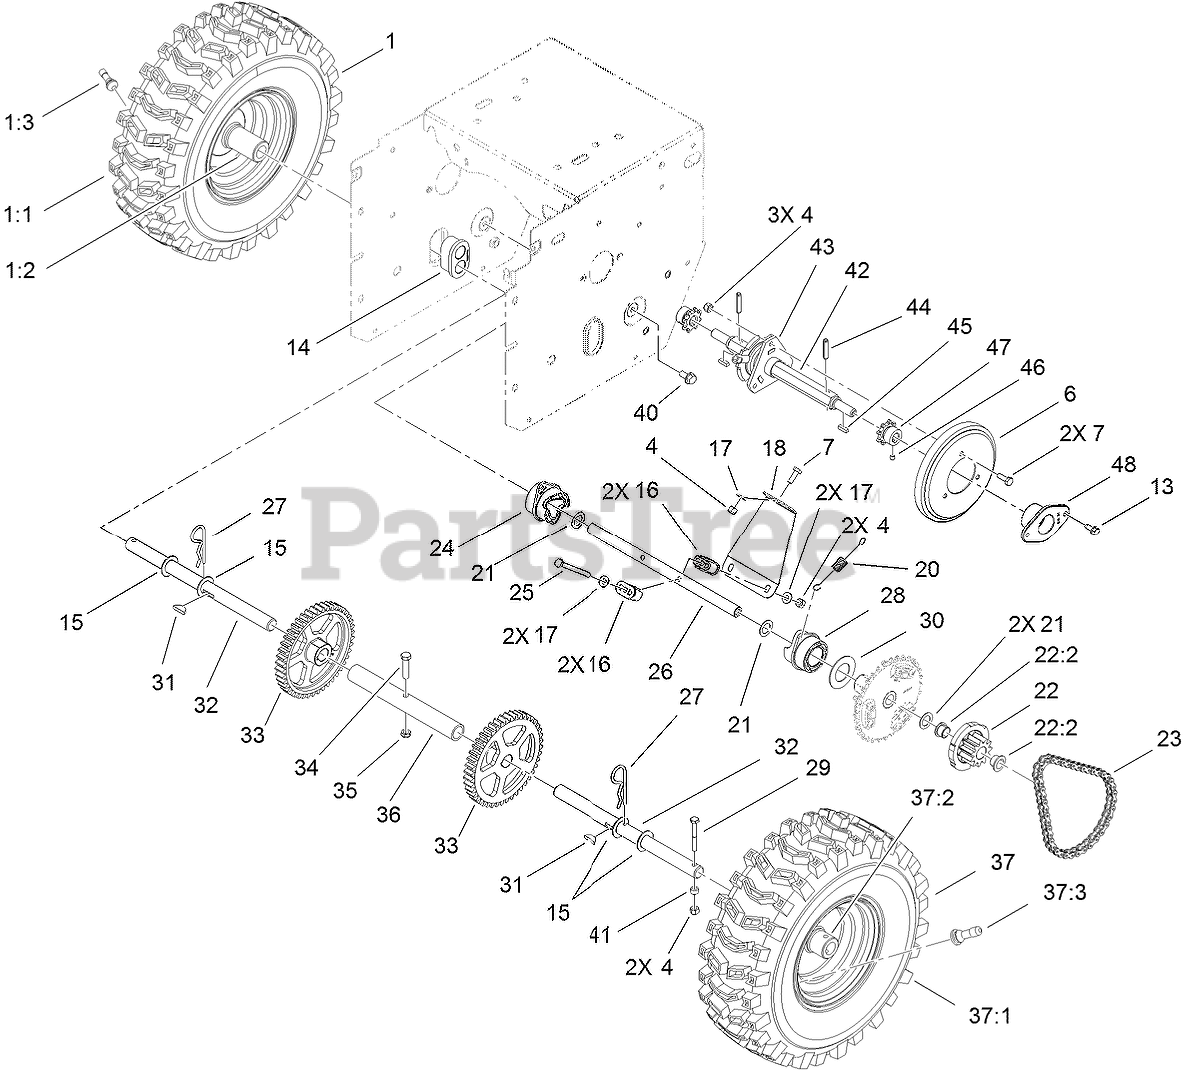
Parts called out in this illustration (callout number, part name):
1	RH WHEEL AND TIRE ASM
1:2	RIM-TIRE
1:3	STEM-VALVE
4	NUT-LOCK, NI
6	WHEEL-FRICTION
7	SCREW-HH
13	SCREW-HWH
14	BEARING-AXLE
15	WASHER-THRUST
16	GUIDE-COLLAR
17	WASHER-FLAT
18	BRACE-COLLAR, SHIFT
20	SPRING-EXTENSION
21	WASHER-FLAT
22	11T GEAR ASM
22:2	BUSHING-FLANGE
23	CHAIN-ROLLER
23	LINK-CONNECTING
24	COLLAR-SHIFT, RH
25	SCREW-HH
26	SHAFT-INTERMEDIATE
27	PIN-HAIR
28	COLLAR-SHIFT, LH
29	SCREW-HH
30	WASHER-THRUST
31	KEY-WOODRUFF
32	SHAFT-AXLE
33	GEAR-AXLE, 44 TOOTH
34	SCREW-HH
35	NUT-LOCK, NI
36	TUBE-AXLE
37	LH WHEEL AND TIRE ASM
37:2	RIM-TIRE
37:3	STEM-VALVE
40	SCREW-HWHTF
41	SPACER-BLADE, ROTOR
42	SHAFT-HEX
43	TRUNNION-HEX
44	PIN-ROLL, SLOTTED
45	KEY-SQUARE
46	SCREW-HSH
47	SPROCKET-8 TOOTH
48	RETAINER-BEARING
